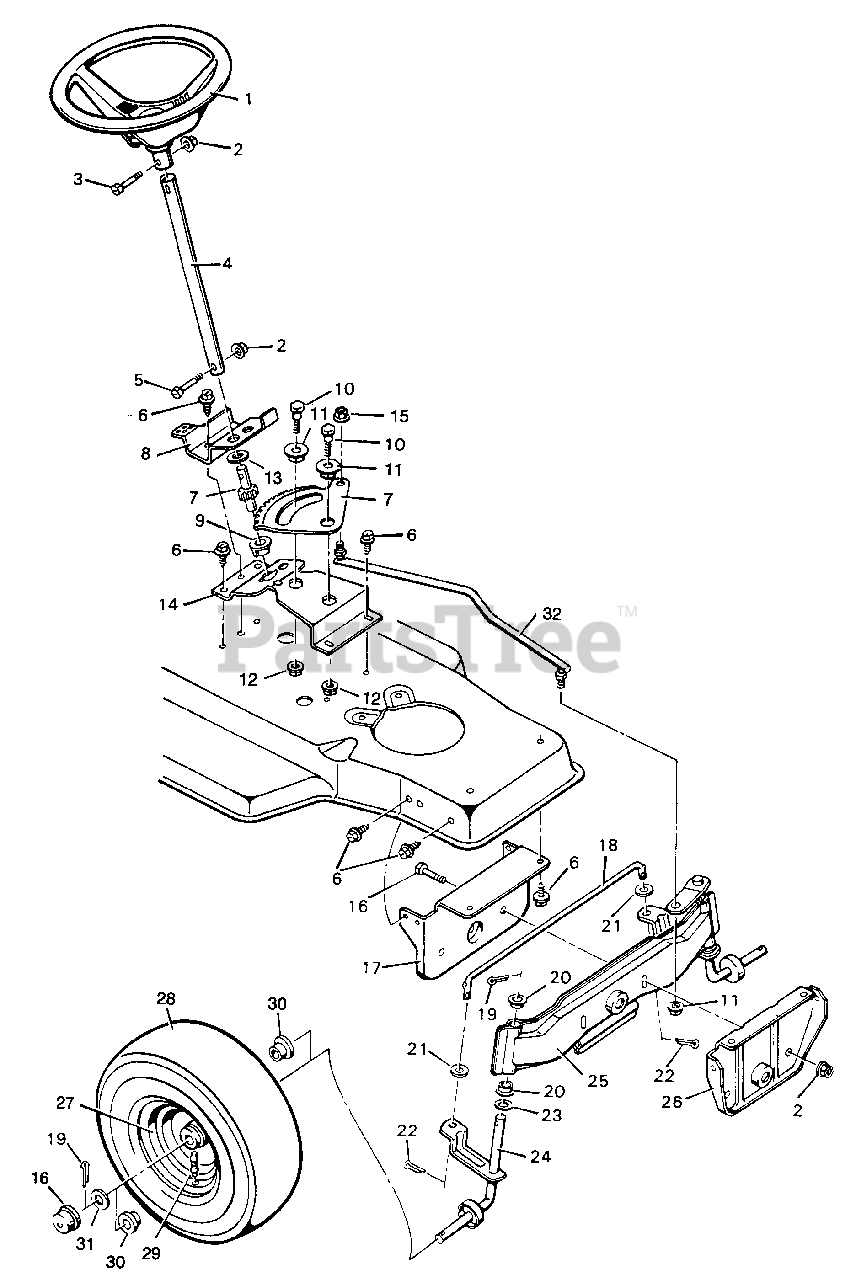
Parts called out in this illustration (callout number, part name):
1	WHEEL- Steering
2	NUT- Hex
3	BOLT- Hex
4	POST- Steering
5	BOLT- Hex
7	GEAR- Sector & Pinion
8	BRACKET- Sector
10	BOLT- Hex
12	NUT- Lock (flange)
14	BRACKET- Sector
15	NUT- Lock (flange)
16	BOLT- Hex
17	SUPPORT- Axle (rear)
18	ROD- Tie
19	PIN- Cotter
21	WASHER
22	PIN- Cotter
24	SPINDLE ASSEMBLY (Right)
25	SPINDLE ASSEMBLY- Axle & Left
26	SUPPORT- Front axle
27	WHEEL & TIRE ASSEMBLY
29	STEM-Valve
30	BEARING- Wheel
32	LINK- Drag
